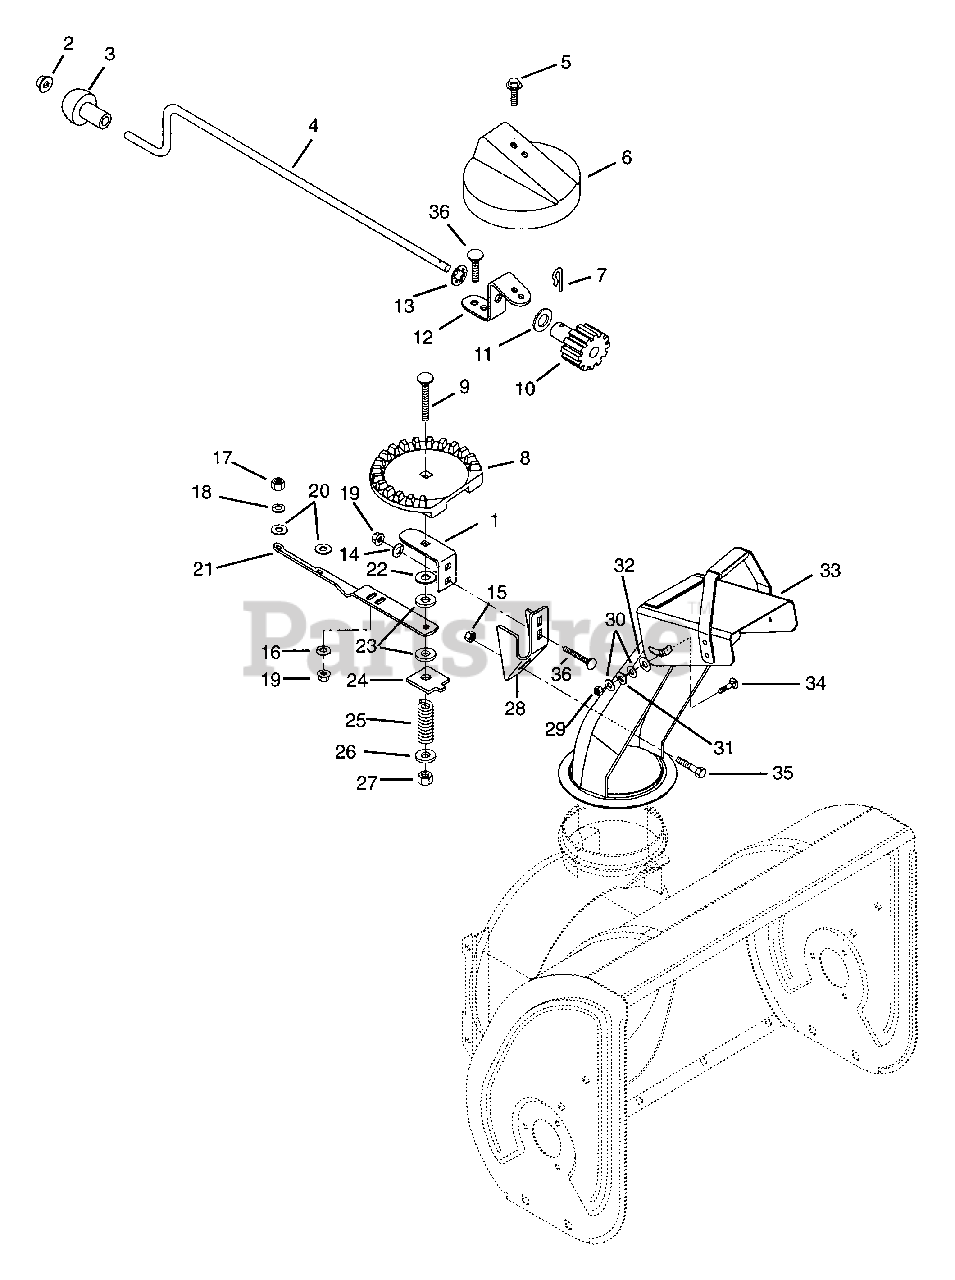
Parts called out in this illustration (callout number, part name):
1	GEAR STRAP
2	CAP, 3/8 ROD YWZC
4	CHUTE CRANK
5	@SCR-TAP .25-20X.50 HWH TR YWZ
6	GEAR COVER
7	PIN, SPRING CLIP
8	CHUTE GEAR
9	@BLT-RDHDSQNK .38-16X2.50 G5YZ
10	PINION GEAR W/BRACKET
11	WSHR-FL-STL .630X1.005X.062 YZ
12	BRACKET-GEAR
13	PUSHNUT .625
14	@WSHR-LK .25X.062 REG YWZC
15	@NUT-LK-CTR .25-20 YWZC
16	@WSHR-LK .25X.062 REG YWZC
17	@NUT-HEX .31-18 YWZC
18	WSHR-LK .312X.097 HVY YWZC
19	@NUT-HEX .25-20 YWZC
20	WSHR-FL-STL .328X.875X.062YWZC
21	BRACE, CHUTE CONTROL
22	WSHR-FL-STL .380X1.50X.062 YWZ
23	FRICTION WASHER
24	FRICTION PLATE
25	SG-COMP .187X.56X1.62
26	@WSHR-FL-STL.406X.812X.065 YWZ
27	@NUT-LK-CTR .38-16 YWZC
28	CHUTE STRAP
29	@NUT-LK-CTR .31-18 YWZC
30	WSHR-FL-STL .323X.625X.062 YWZ
31	WAVE WASHER .390X.655X.110
32	WSHR-PLASTIC .390X.875X.062
33	CHUTE, DISCHARGE W/CAP & DECAL
34	@BLT-RHDSSQNK .31-18X.75 G5YZ
35	@BLT-HEX .25-20X.50 GR5 YWZC
36	@BLT-RDHDSQNK .25-20X.75 G5YZ
